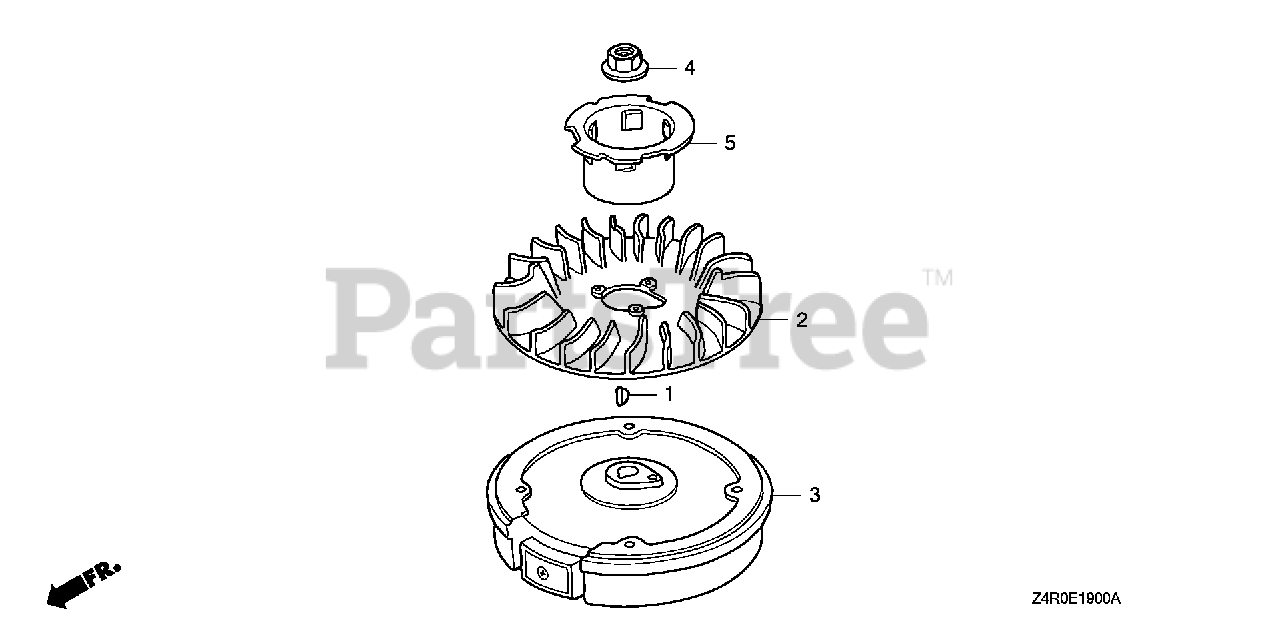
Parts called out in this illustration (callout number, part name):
1	KEY, SPECIAL WOODRUFF (25X18)
2	FAN, COOLING
3	FLYWHEEL (STD)
4	NUT, SPECIAL (14MM)
5	PULLEY, STARTER
